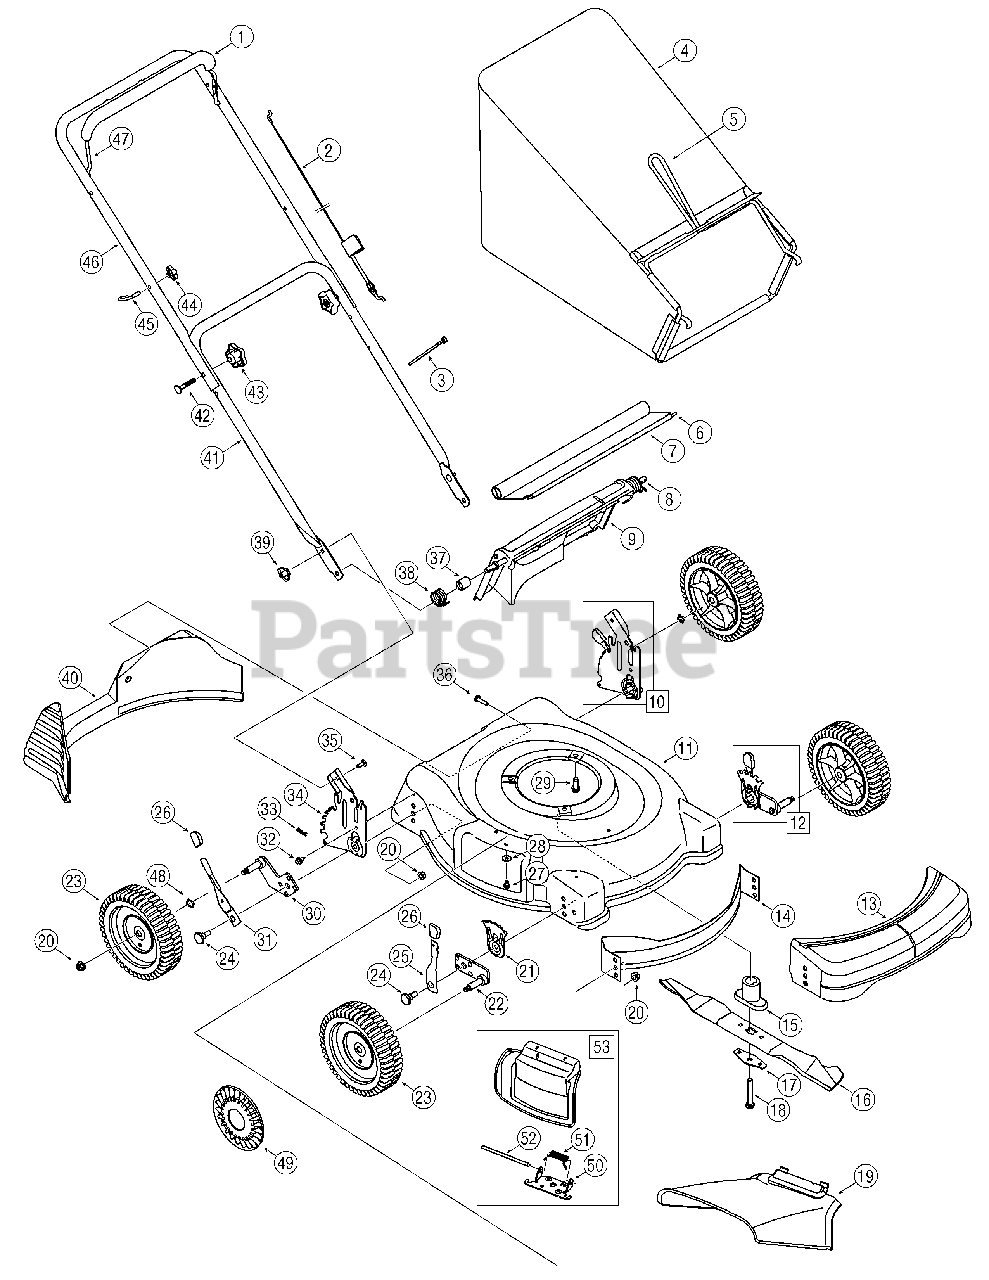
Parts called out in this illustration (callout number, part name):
1	Bail Cover
2	Control Cable 40-inch
3	Cable Tie
4	Grass Bag Assembly
6	Trailshield Wire
7	Trailshield
8	Pivot Rod
9	Rear Door
10	Height Adj. Bracket Assy - LH
10	Height Adj. Bracket Assy - RH
12	Hgt. Adj. Assy - RH (8-inch Whl)
13	Front End Cover, 21-inch
14	Front Baffle
15	Blade Adapter
16	21-inch Mulching Blade
17	Bell Blade Support
18	Hex Bolt 3/8-24 x 2.5
19	Side Discharge Chute
20	Flange Lock Nut 3/8-16
21	Height Adjustment Plate
22	Pivot Arm Assy - RH
22	Pivot Arm Assy - LH
23	Wheel 8 x 2.125 COG Idle BB
24	Shoulder Screw .5 x .434
25	Spring Lever
26	Height Adjust Knob
27	TT Screw 1.4-20 x .50
28	Bell Washer .265 x .75 x .062
29	TT Sems Screw 3.8-16 x 1.00
30	Pivot Arm Assy - RH
30	Pivot Arm Assy - LH
31	Spring Lever
32	TT Screw 1/4-20 x .625
33	Int. Cotter Pin .072 dia. X 1.13 lg
34	Rear Handle Bracket - RH
34	Rear Handle Bracket - LH
35	Carriage Screw 1/4-20 x .75
36	Screw HL 1/4-15 x 1.00
37	Spacer
38	Torsion Spring - RH
38	Torsion Spring - LH
39	Wing Nut
40	Rear Baffle
42	Carriage Bolt 5/16-18 x 2.0
43	Star Knob
44	Handle Knob
48	Wave Washer .51 x .75 x 1.68
49	Hubcap
50	Chute Deflector Adapter
51	Torsion Spring .290 ID x 1.68
52	Hinge Pin
53	Mulch Plug Assembly
